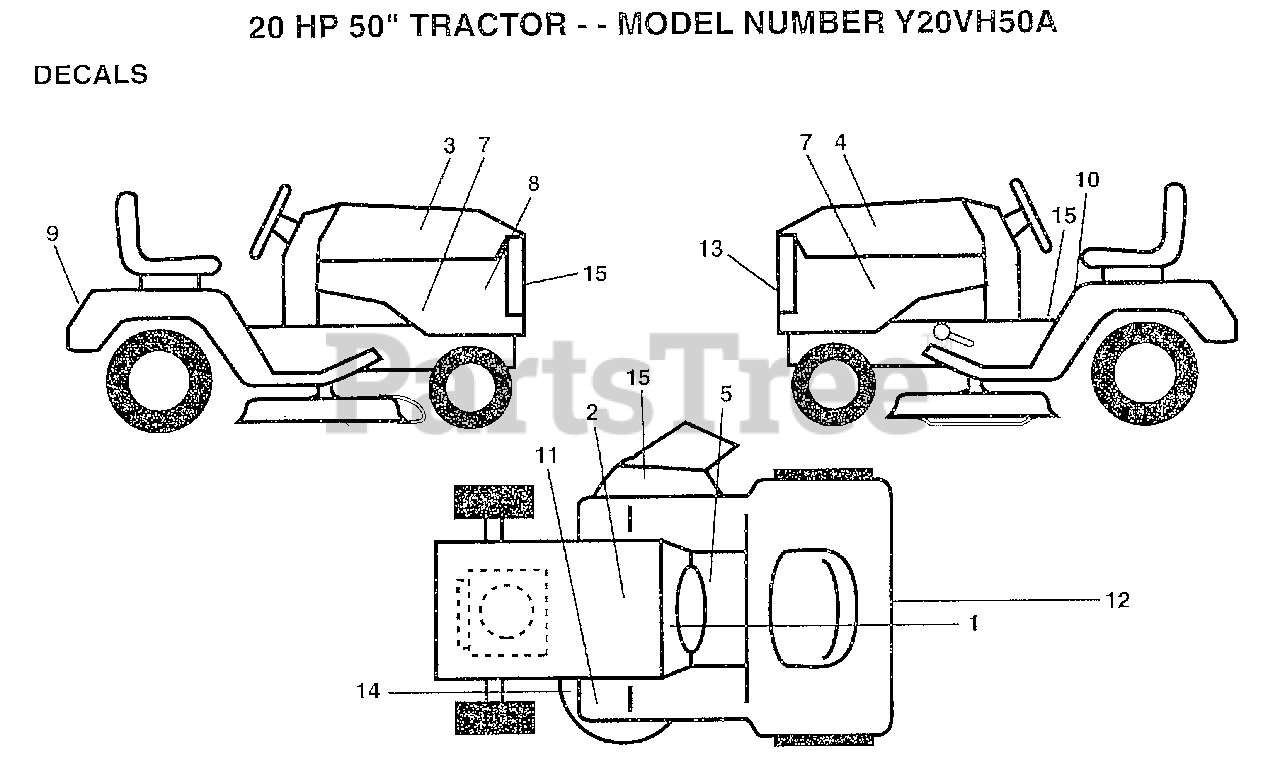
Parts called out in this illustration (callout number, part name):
1	DECAL.DASH.INSTR.
2	DECAL
4	DECAL HOOD LH
5	DECAL BRAK PARK
7	DECAL.PNL.SIDE.20
8	DECAL SADL HYDRO
10	DECAL CAUTION
11	DECAL T
12	DECAL D-BAR CNTRL
13	DECAL.GRILL.YARDP
14	"DECAL.V.BELT.44"""
15	"DECAL, WARNING"
